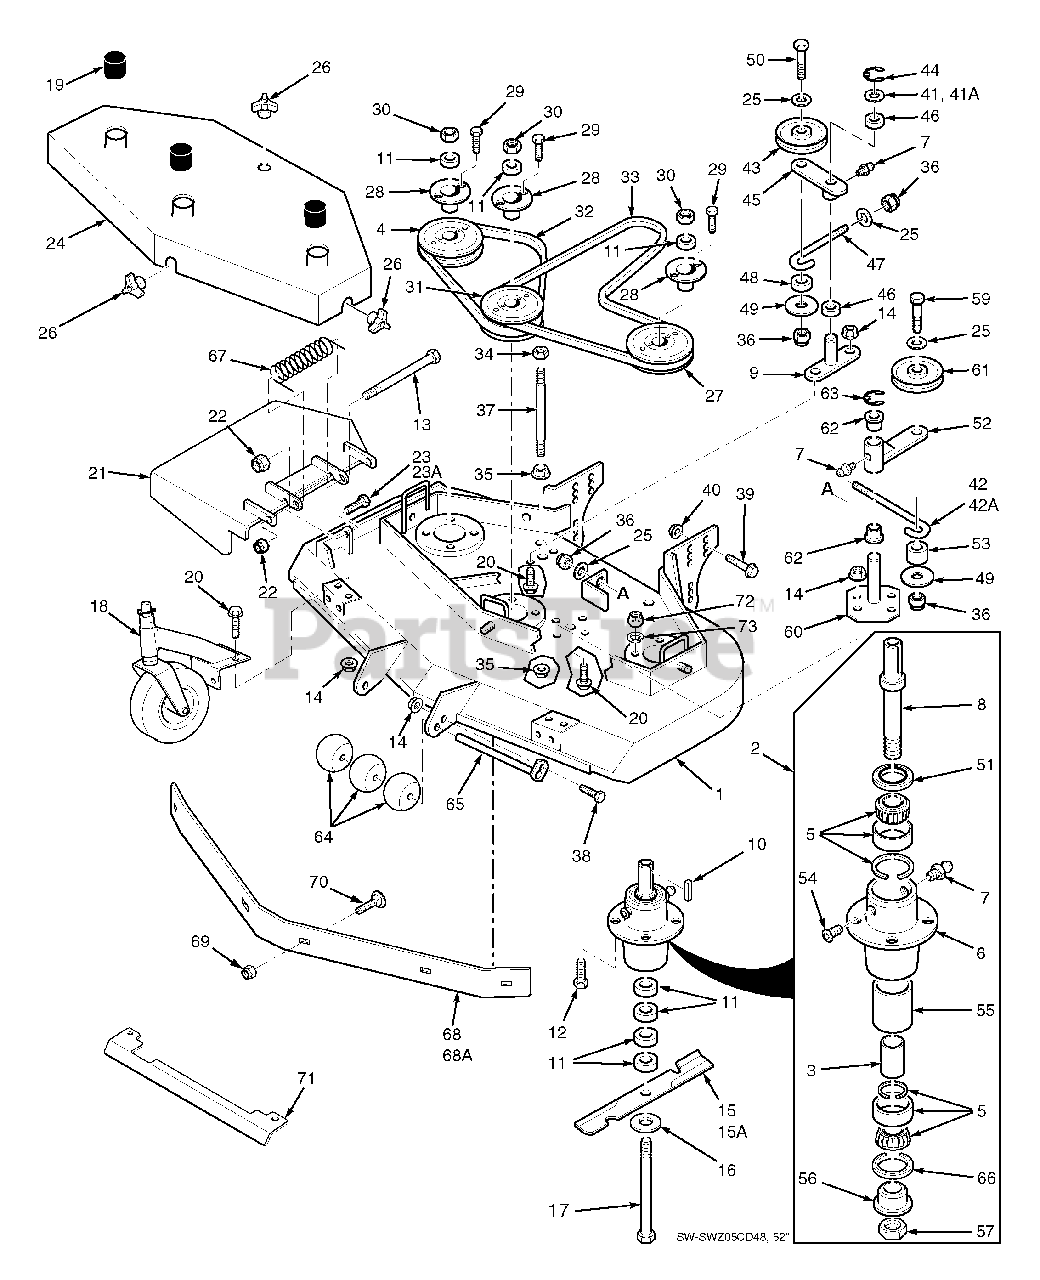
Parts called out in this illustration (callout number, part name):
1	Cutter Deck
2	Spindle Assembly
3	Spacer, Inside
4	Pulley
5	Tapered Bearing (Two)
6	Spindle Housing
7	Grease Fitting Str. 5/16"
8	Spindle Shaft, Tapered Brng
9	Idler Pivot
10	Key, 1/4 x 1/4 x 2"
11	Spacer, Cutter Blade - Small
12	Bolt, 5/16-18 x 1-1/2" Hex Head GR-8
13	Bolt, 5/16-18 x 4-3/4" Hex Head
14	Serrated Flange Nut, 5/16-18
15	Cutter Blade 16-1/2" Marbain
15	Cutter Blade 18" Marbain
15A	Cutter Blade 16-1/2 High Lift Marbain
15A	Cutter Blade 18 High Lift Marbain
16	Flatwasher,5/8" (.688 x 1.75 x .134)
17	Hex Head Bolt, 5/8-11 x 9-1/2"
18	Caster Assembly
19	Spindle Shield
20	Capscrew, 5/16-18 x 3/4"
21	Discharge Chute
22	Nut, 5/16-18 Elastic Elastic Stop
23	Bolt, 5/16-18 x 1-1/2" Hex Head (Front)
23A	Bolt, 5/16-18 x 1-3/4" Hex Head (Rear)
24	Belt Cover
25	Flat Washer, 3/8" Special
26	Wing Nut, 3/8-16 (Large)
27	Pulley
28	Tapered Hub
29	Bolt, 1/4-20 x 1" Hex Head Grade 8
30	Nut, 5/8-11 Hex
31	Pulley, Double
32	Belt, RH Blade Drive
33	Belt, Blade Drive
34	Nut, 3/8-16, Nut Centerlock
35	Nut, 3/8-16, Serrated Flange
36	Nut, 3/8-16 Elastic Stop
37	Support, Belt Cover
38	Bolt, 5/16-18 x 1" Hex Head
39	Cpscrw, 1/2-13 x 1" Ser.Flg. HH
40	Nut, 1/2-13 Spiralock
41	Flat Washer 3/4" Special
41A	Flat Washer 3/4" Special
42	J-Hook
42A	J-Hook
43	Idler Pulley, “V” Groove
44	Retaining Ring, 3/4" Ext.”E”
45	Idler Arm Assy.
46	Bronze Bearing
47	J-Rod, Idler Pulley
48	Spacer, J-Rod
49	Washer, 3/8 x 1-1/2 x 16 ga.
50	Bolt, 3/8-16 x 2-1/4" Hex Head
51	Seal, Cutter Spindle
52	Idler Arm Assy
53	Spacer, J-Rod
54	Reiief Fitting, Cutter Spindle
55	Spacer, Outside, Cutter Spindle
56	Spindle Bushing
57	Nut, Cutter Spindle
58	Wing Nut, 3/8-16
59	Bolt, 3/8-16 x 3-1/2" Hex Head
60	Idler Pivot
61	Idler Pulley, Belt Clutch
62	Bronze Bearing
63	Retaining Ring
64	Guide Roller
65	Roller Shaft
66	Seal, Cutter Spindle
67	Spring, Chute Return
68	Baffle Weldment 48A
69	Nut, Hex Elastic Stop 3/8-16
70	Bolt, Carriage 3/8-16 x 1"
71	Heatshield
72	Nut, Hex Lock 5/16-18
73	Lock Washer 5/16
